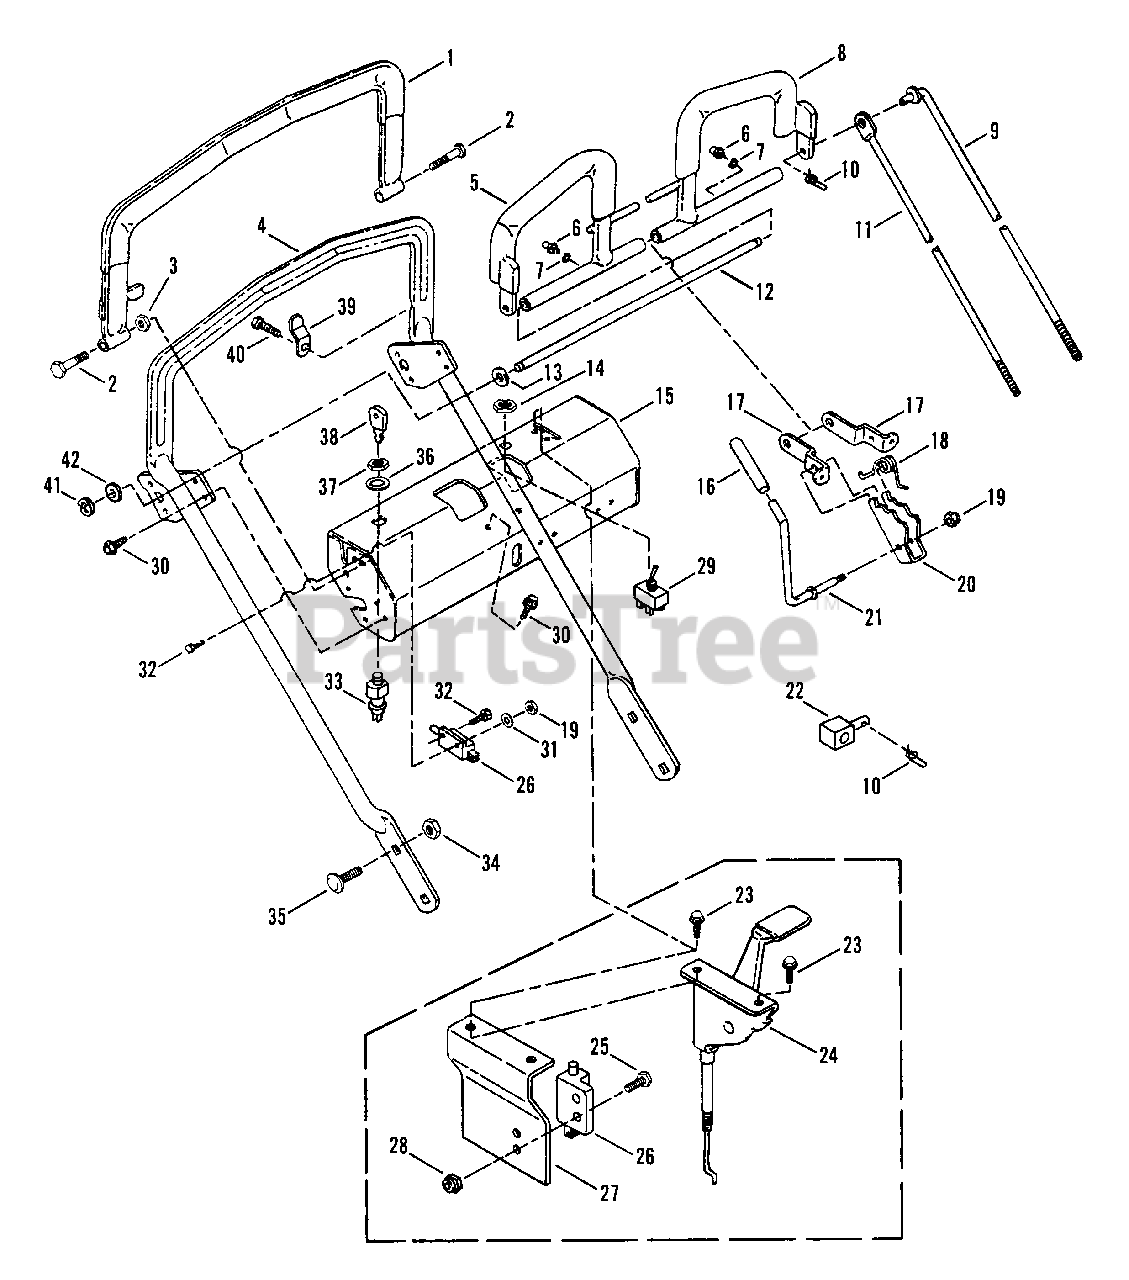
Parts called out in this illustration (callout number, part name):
1	BAIL, OPC (With Grip)
2	BOLT, 1/4-20 X 1-3/4" GD5 YZ
2	NUT, 3/8-16 HEX NYLOCK FLANGE
3	NUT, 1/4-20 Hex
3	WASHER, 3/8 SAE
4	BOLT, 3/8-16 X 3-1/2" GD5 CZ
5	SPACER, .51 X .75 X .56
6	SPACER, .38 X .50 X 1.25
7	BOLT-WHEEL 3/8-16X2.781 .750 THRD YELLOW
8	WASHER-0500(0.51IDX0.87ODX.06THK) BLK
9	GAUGE WHEEL
12	ROD, Pivot
13	WASHER, 1/2 Flat
14	NUT, 1/2-27 (Special)
15	CONTROL, Console
16	GRIP, Neutral Latch
17	BRACKET, Neutral Mounting
18	SPRING, Neutral
19	NUT, 1/4-20 Hex Nyloc
20	LATCH
21	LEVER, Neutral Latch
22	SWIVEL
23	SCREW, #10-24 x 1/2" Hex Washer Self-Tap (Torx)
24	CONTROL, Throttle (Kohler)
25	SCREW, #10-24 x 1/2" Hex Head, Machine
26	SWITCH, OPC
27	BRACKET, Reverse Throttle
28	NUT, #10-24 Hex Nyloc
29	SWITCH
30	SCREW,1/4-20 x 1/2" Self-Tapping
31	WASHER, 1/4 Flat
32	SCREW, #12-14 x 1/2" Hex Slotted Head, Self-Tapping
33	SWITCH, ON-OFF
34	NUT, 3/8-16 HEX NYLON LOCK
35	BOLT, 3/8-16 x 1" Carriage
36	WASHER, 5/8 Internal Tooth Lock
37	NUT, 5/8-32 Hex (Special)
38	KEY, Switch (With Cover)
39	SPRING, Loop Handle
40	SCREW, 1/4-20 x 3/8" Hex Washer Head, Self-Tapping
41	E-RING, 1/2"
42	BUSHING, 1/2" Machine
